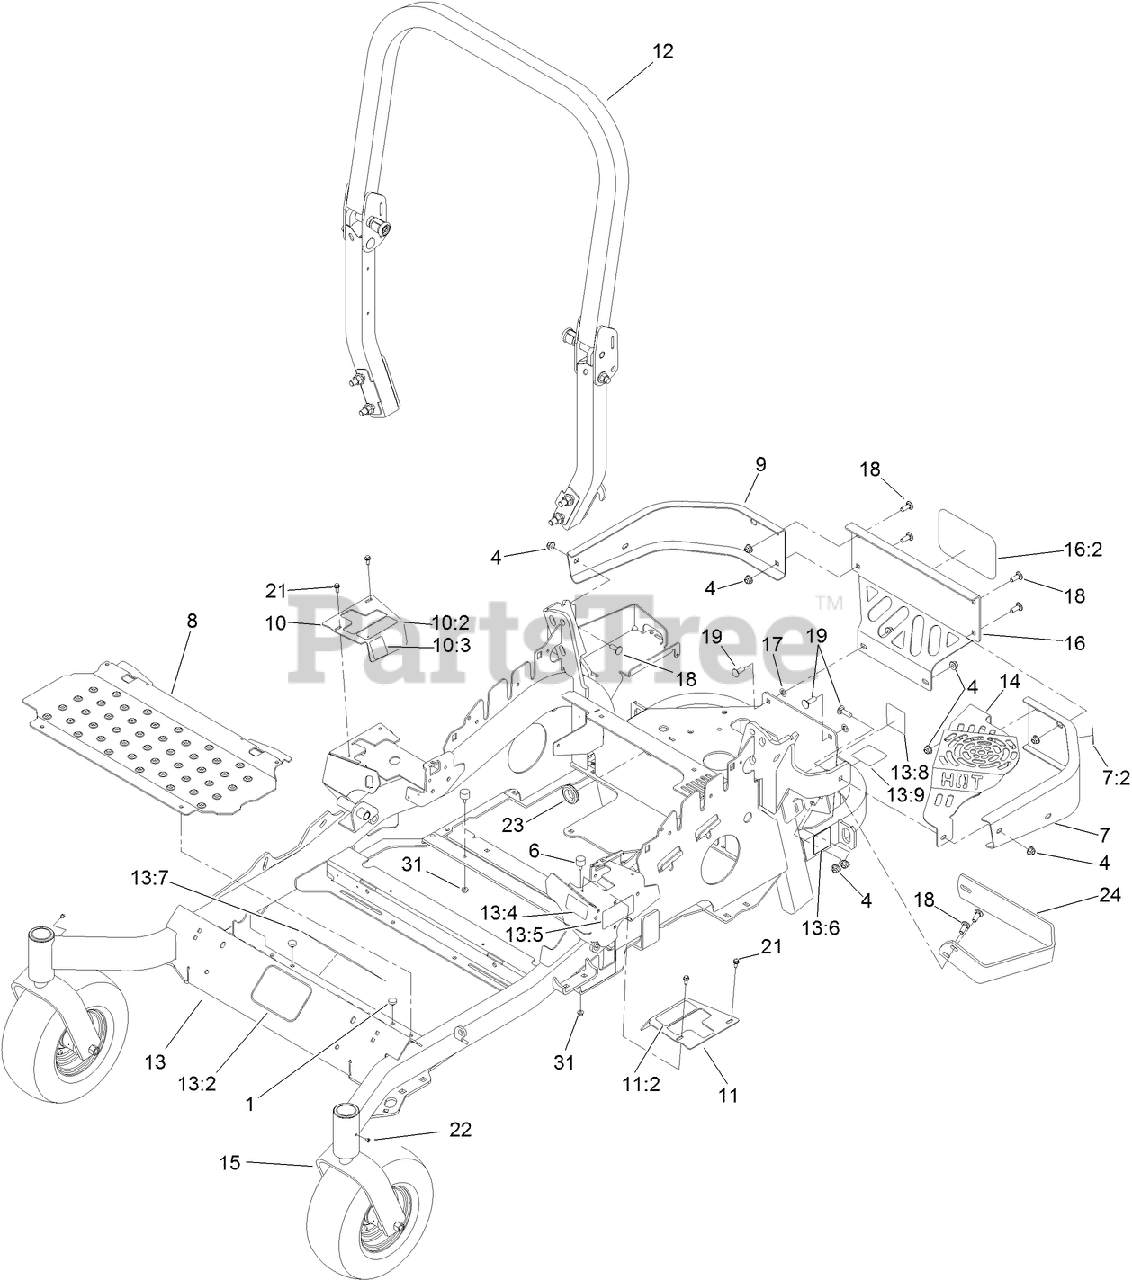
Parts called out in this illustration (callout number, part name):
1	BUMPER
4	NUT-HF, NI
6	BUMPER-RUBBER (W/ STUD)
7	BUMPER-REAR, LH
7:2	DECAL-CAUTION
8	FLOORPAN
9	BUMPER-REAR, RH
10	COVER ASM-MOTION CONTROL
10:2	DECAL-MOTION CONTROL
10:3	DECAL-PARK BRAKE
11	COVER ASM-MOTION CONTROL
11:2	DECAL-MOTION CONTROL
12	ROPS ASM
13	FRAME ASM
13:2	DECAL
13:4	DECAL-FUEL FILL
13:6	DECAL-BELT DRIVE
13:7	DECAL-SLOPE
13:8	DECAL-SPARK ARRESTER
13:9	DECAL-BYPASS
14	GUARD-MUFFLER
15	Caster Wheel ASM
16	REAR GUARD ASM
16:2	DECAL
17	NUT-PUSH
18	SCREW-CARR
19	BOLT-CARR
21	SCREW-HWH
23	GROMMET
24	GUARD-MUFFLER, SIDE
31	NUT-HF
